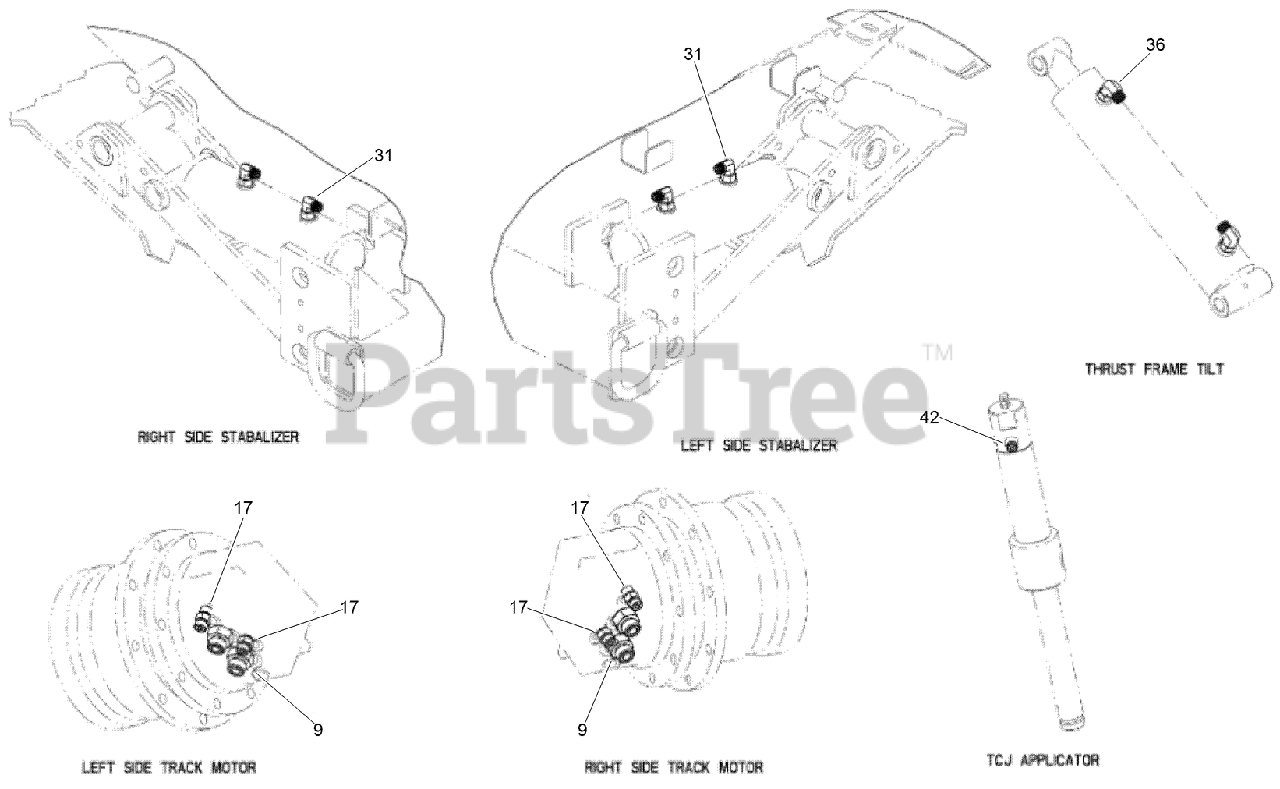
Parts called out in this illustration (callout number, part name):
9	CONNECTION - Straight, -8 ORFS / -10 ORB
17	CONNECTION - Straight, -4 ORFS / -6 ORB
31	CONNECTION - 90 Deg, -4 ORFS / -6 ORB
36	CONNECTION - 90 Deg, -6 ORFS / -6 ORB
42	CONNECTION - Straight, -4 ORFS / -4 ORB
